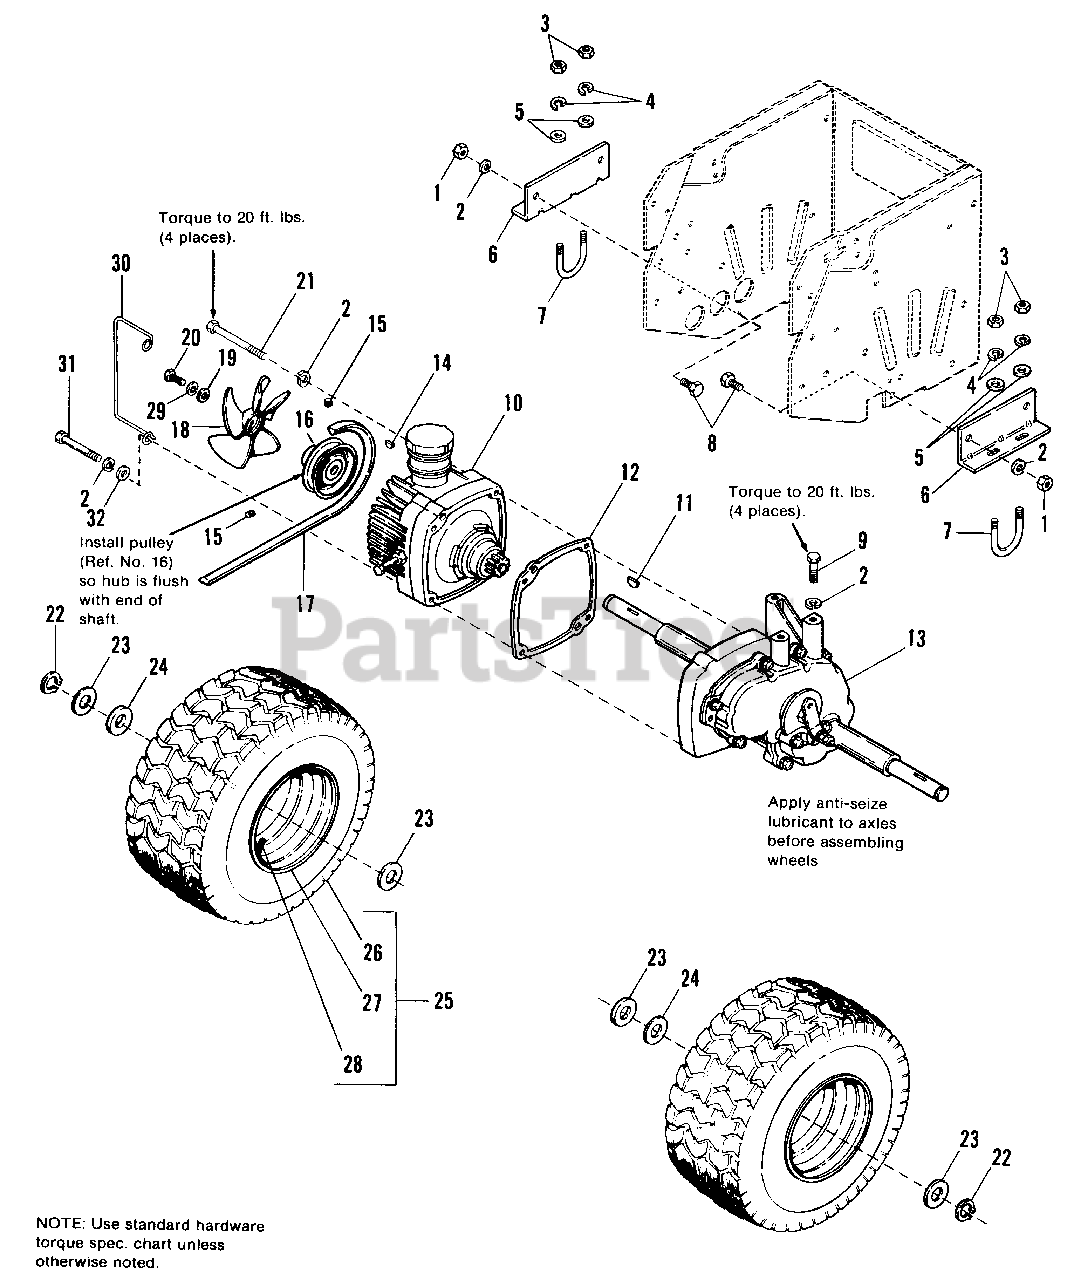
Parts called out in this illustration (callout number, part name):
1	NUT, Hex, 3/8-16
2	LOCKWASHER, 3/8
3	NUT, Hex, 5/16-18
4	LOCKWASHER, 5/16
5	WASHER, 5/16
6	SUPPORT, Transmission
7	"U" BOLT, Axle
8	CAPSCREW, Hex, 3/8-16 x 3/4
9	CAPSCREW, Hex, 3/8-16 x 1
10	TRANSMISSION, Hydrostatic (See page 15 for parts list)
11	KEY, Woodruff, #18, 1/4 x 1-1/4
13	GEAR REDUCTION & DIFFERENTIAL ASSY.
14	KEY, Woodruff, #3, 1/8 x 1/2
15	SETSCREW, Hex Soc. Cup., 1/4-28 x 1/4
16	PULLEY, Transmission
17	BELT, "V" Drive
18	FAN, 7" Diameter
19	WASHER, 1/4 x 1-1/4 x 14 Ga.
20	CAPSCREW, Hex, 1/4-2 x 1/2
21	CAPSCREW, Hex, 3/8-16 x 3
22	RING, Retainer
24	WASHER, Plain, 1 x 1-3/4 x 1/4
25	WHEEL & TIRE ASSY.
26	TIRE, 20 x 10-10
27	WHEEL ASSY.
28	VALVE STEM & CAP
29	LOCKWASHER, 1/4
30	BELT STOP
31	CAPSCREW, 3/8-16 x 3-1/4
32	WASHER, 3/8
